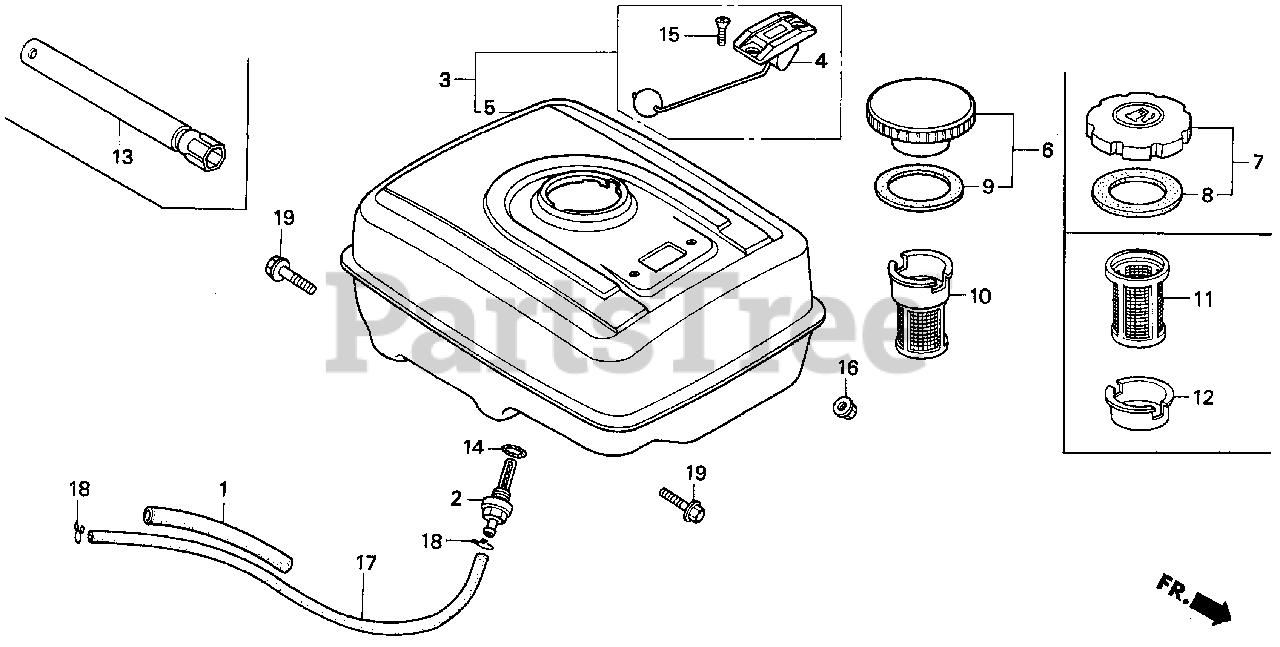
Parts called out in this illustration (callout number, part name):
1	RUBBER, SUPPORTER (107MM)
2	JOINT, FUEL TANK
5	TANK, FUEL *NH31* (MCKINLEY WHITE)
5	TANK, FUEL *NH1* (BLACK)
7	CAP, FUEL FILLER
8	GASKET, FUEL FILLER CAP
10	FILTER, FUEL
13	WRENCH, SPARK PLUG
14	O-RING (13.5X1.5) (ARAI)
16	NUT, FLANGE (8MM)
17	BULK HOSE, FUEL (4.5X3000) (4.5X222)
18	CLIP, TUBE (B8)
19	BOLT, FLANGE (8X25)
